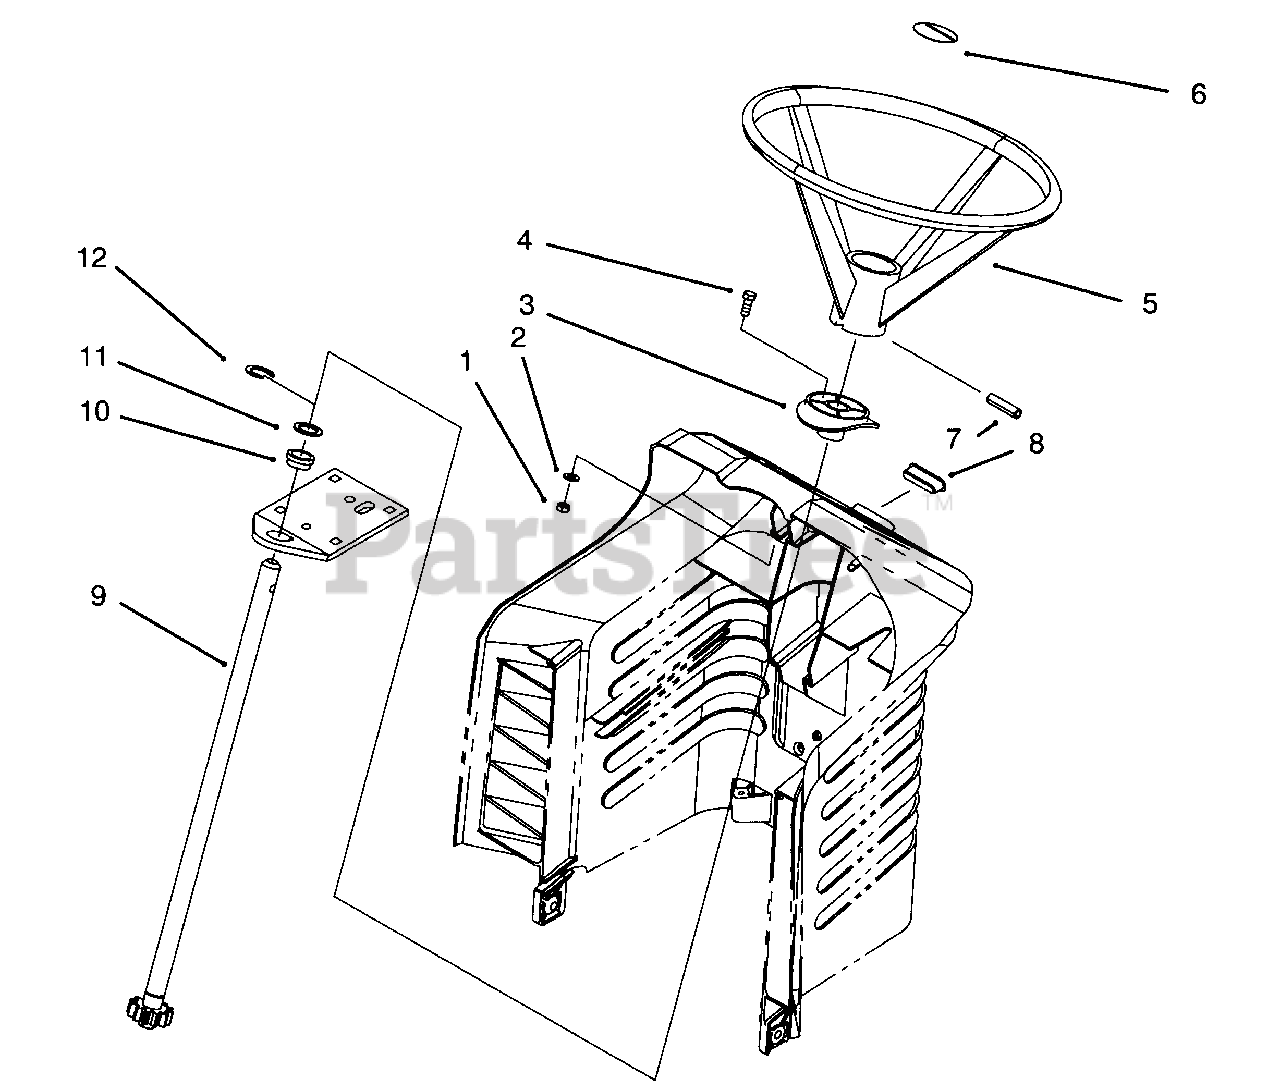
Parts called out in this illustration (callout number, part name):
1	Nut-Lock
2	Washer-Flat
3	Bushing-Sliding
4	Screw-Hex Hd. Cap
5	Wheel-Steering (Incl. Ref. #6)
6	Insert-Steering Wheel
9	Shaft-Steering
10	Bushing-Flange
11	Washer-Thrust
